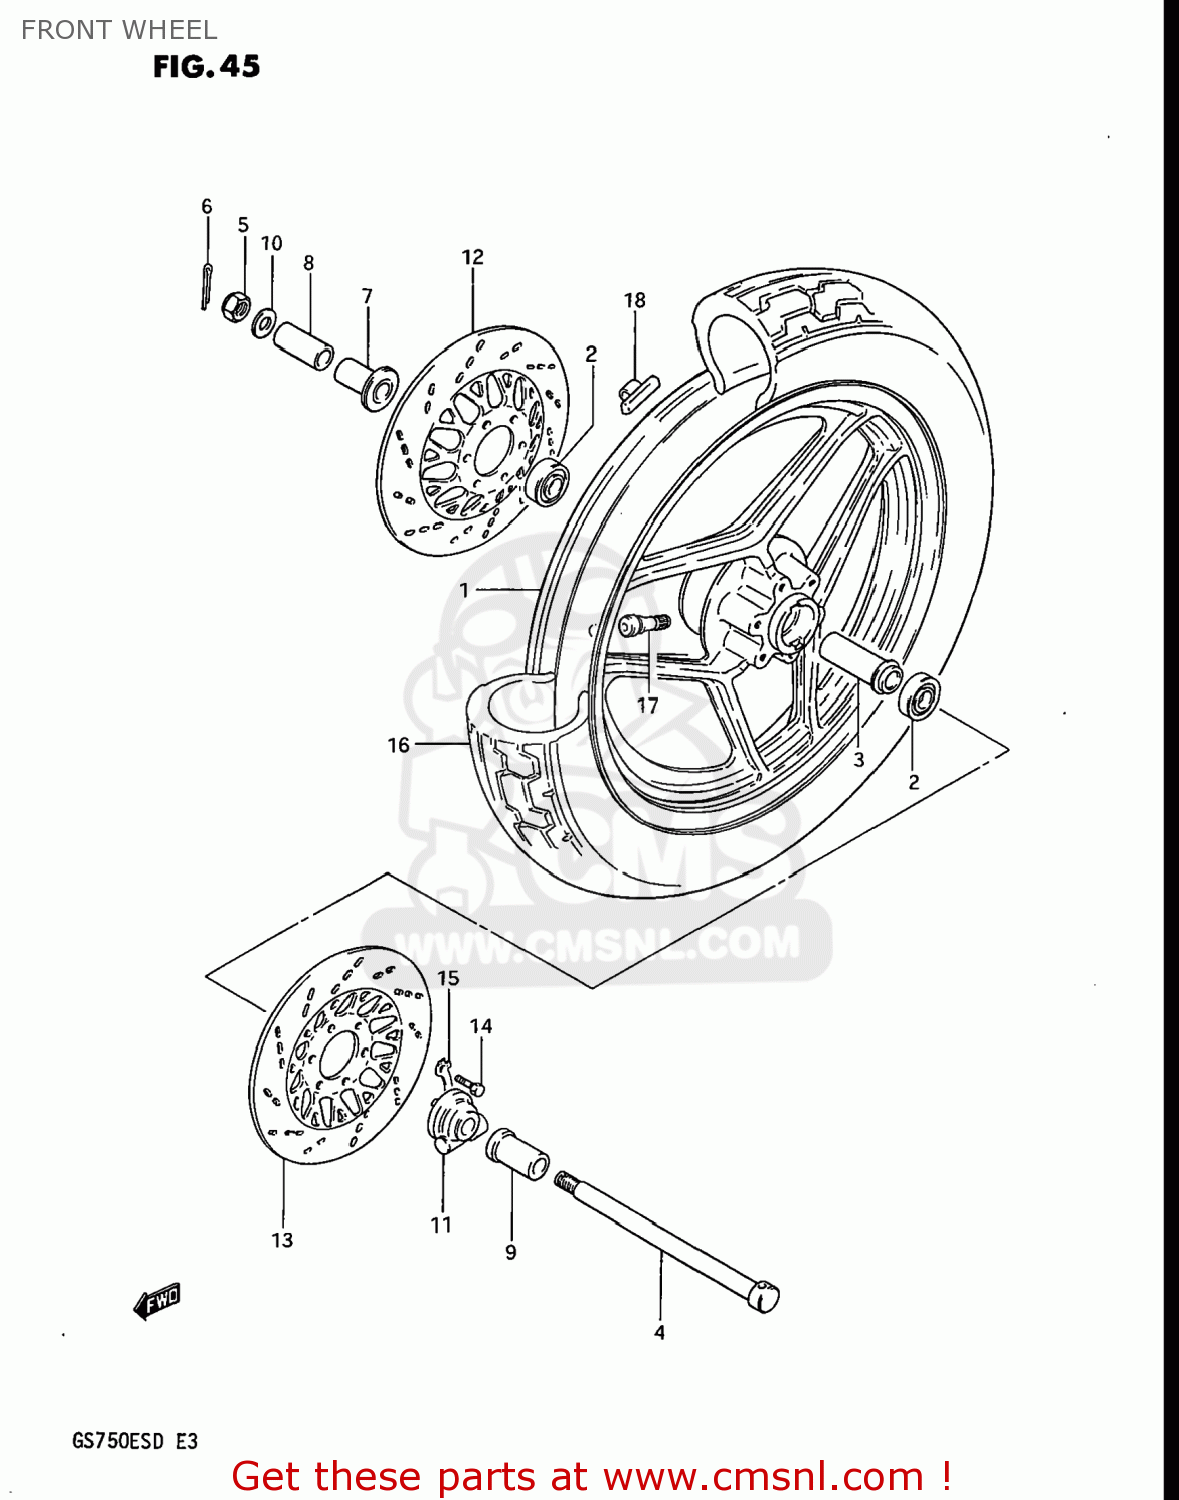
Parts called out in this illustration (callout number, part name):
1	CASTING WHEEL,FRONT 2.15
2	BEARING
3	SPACER,FRONT HUB BEARING
4	AXLE,FR
5	NUT 12MM
6	COTTER PIN
7	SPACER,FR AXLE,R
8	SPACER,FR AXLE,R
9	SPACER,FR AXLE,L
10	WASHER
11	BOX ASSEMBLY,SPEEDOMETER GEAR
12	DISC,BRAKE,RIGHT
13	DISC,BRAKE,LEFT
14	BOLT(8X25)
15	WASHER
16	TIRE,FRONT
17	VALVE,TIRE
18	BALANCER,WHEEL
